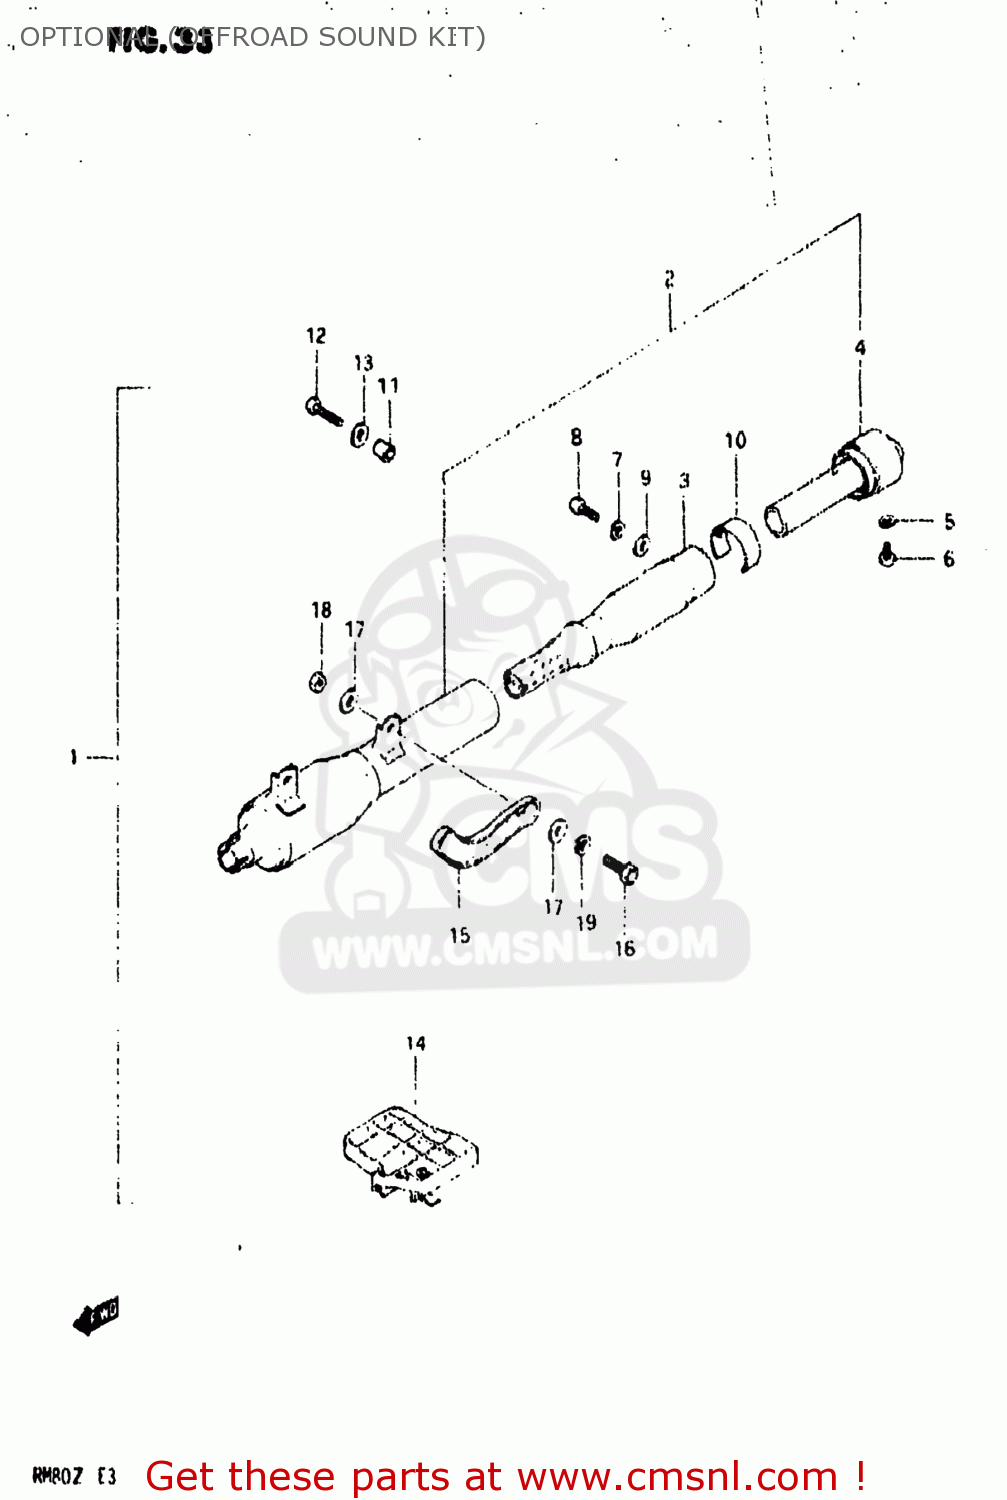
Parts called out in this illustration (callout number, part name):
1	OFF-ROAD SOUND KIT
2	MUFFLER ASSEMBLY
3	ARRESTER,SPARK
4	TUBE,MUFFLER CLEAN OUT
5	LOCK WASHER
6	SCREW
7	LOCK WASHER
8	SCREW(6X8)
9	WASHER
10	BAND,SPARK ARRESTER
11	SPACER (6.8X10X10)
12	SCREW, NO. 1
13	WASHER
14	DRAIN TUBE,AIR CLEANER
16	BOLT
17	WASHER
18	NUT
19	LOCK WASHER
